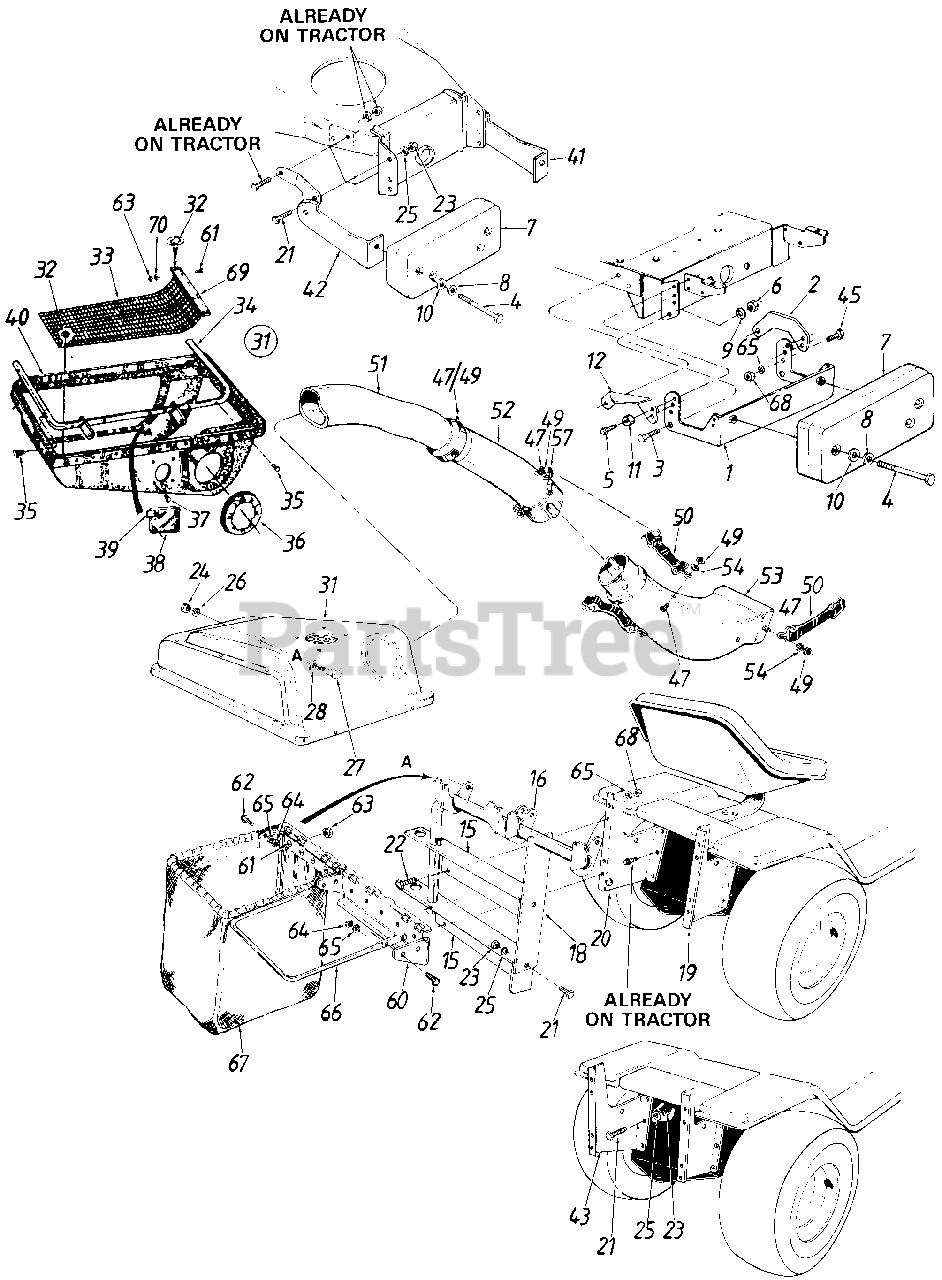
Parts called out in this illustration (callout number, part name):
1	Weight Brkt. Ass'y.
2	Weight Brkt. Tie Strap-L.H.
3	Hex Bolt 7/16-20 x 1.0" Lg.*
4	Hex Bolt 3/8-16 x 4.5" Lg.*
5	Hex AB Tap Scr. 5/16-18 x l.O"
6	Hex Jam Nut 7/16-20 0 Thd.
7	Front Counter Weight 38 Ibs.
8	Bell.-Wash. 400" I.D. x .88" O.D.
9	L.-Wash. 7/16" I.D.
10	Fl.-Wash. .390" I.D. x 1.12" O.D.
11	Spacer
12	Weight Brkt. Tie Strap-R.H.
15	Catcher Support Tube Mtg. Brkt
16	Catcher Support Tube Ass'y.
18	Catcher Latch and Support Brkt.
19	Grass Catcher Support Brkt-R.H.
20	Grass Catcher Support Brkt.-LH.
21	Hex Bolt 5/16-18 x .75" Lg.*
22	Hex Bolt 1/4-20 x .62" Lg.-Grade 5
23	Hex Nut 5/16-18 Thd.*
24	Hex Nut 3/8-16 Thd.*
25	L.-Wash. 5/16" I.D.*
26	L.-Wash. 3/8" I.D.*
27	Shld. Bolt 3/8-16 x .500" Dia.
28	Bell.-Wash. .505" I.D. x 1.00" O.D.
31	Grass Catcher Cover Ass'y.
32	Twist Fastener
35	Hex Tap Scr. 1/4-20 x .5" N Lg.
36	Seal
37	Truss Mach. B-Tap Scr. #10 0 x .5" Lg.
38	Plastic Plate
39	Speed Nut
40	Grass Catcher Cover
41	Weight Brkt. Ass'y. L.H.
42	Weight Brkt. Ass'y. R.H.
43	Grass Catcher Support Brkt.
45	Hex Bolt 1/4-20 x .88" Lg.
47	Hex Bolt 1/4-20 x .50" Lg.*
49	Hex Ins. L.-Nut 1/4-20 Thd.
50	Retainer Strap Ass'y.
51	Catcher Elbow
52	Catcher Tube
53	Discharge Chute
54	L.-Wash. .270" I.D. x .57" O.D.
57	Retainer Hook Brkt.
61	Truss Mach. Scr. #10-24 0 x .50" Lg.
62	Hex Bolt 1/4-28 x .75" Lg.
63	Hex Sems Nut #10-24 0 Thd.
64	Hex Nut 1/4-28 Thd.*
65	L.-Wash. 1/4" I.D.*
67	Grass Catcher Bag
68	Hex Nut 1/4-20 Thd.*
69	Screen Mtg. Brkt.
70	Flat Wash. 1/4" I.D.
